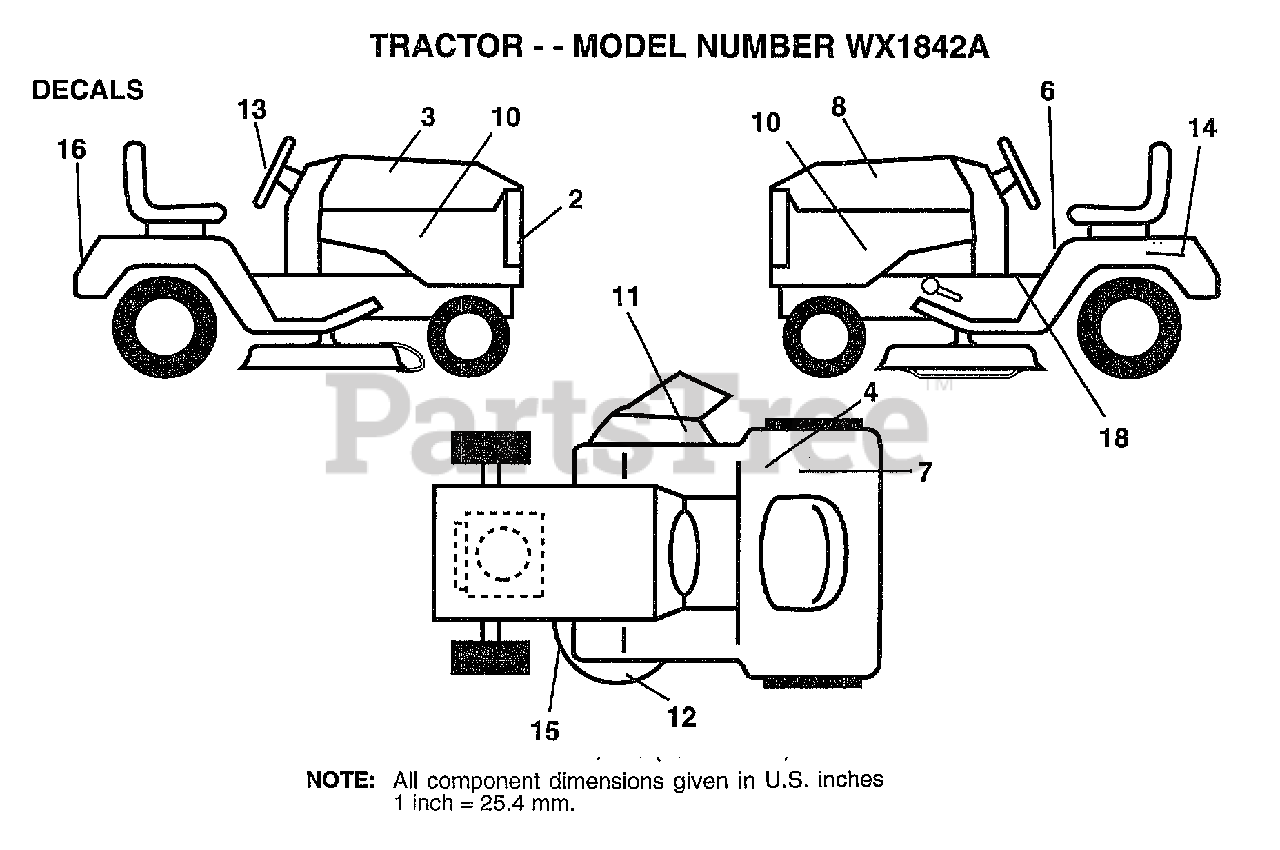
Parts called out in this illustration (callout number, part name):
2	DECAL.GRILL
3	DECAL.HD.STRIP.RH
4	DECAL.EURO.ST.CE.
6	DECAL.READ.O.MANU
8	DECAL.HD.STRIP.LH
10	DECAL.PANEL.SIDE
11	DECAL.DANGER.CUTF
12	DECAL.MOWER
13	DECAL.WHL.STRG.
14	DECAL.BATRY.3-3908
15	DECAL
16	DECAL.FENDER
18	DECAL BRAK PARK
